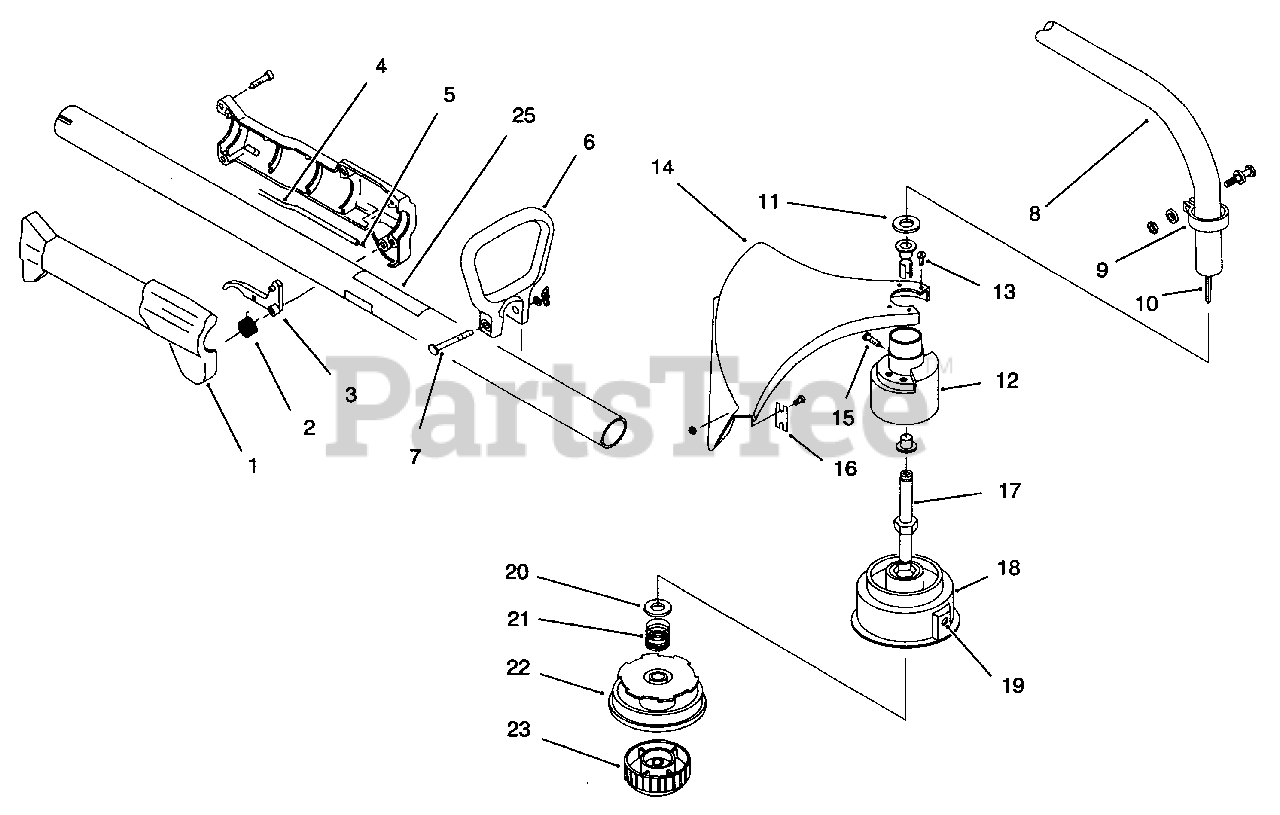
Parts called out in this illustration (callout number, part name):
1	Throttle Housing & Trigger Asm.
2	Throttle Trigger Spring
3	Throttle Trigger
4	Throttle Cable Housing
5	Throttle Cable
6	D-Handle
7	D- Handle Hardware Asm.
8	Drive Shaft Housing Asm.
9	Clamp Asm.
10	Flexible Drive Shaft
12	Bushing Housing Asm.
13	Guard Mounting Screw Asm.
14	Guard and Blade Asm. (Incl. Ref. #16)
15	Anti-Rotation Screw
16	Blade Asm.
17	Spool Shaft
18	Outer Spool and Eyelet Asm.
20	Retainer
22	Inner Reel
23	Bump Head Knob Asm.
25	Decal-Safety Symbols
